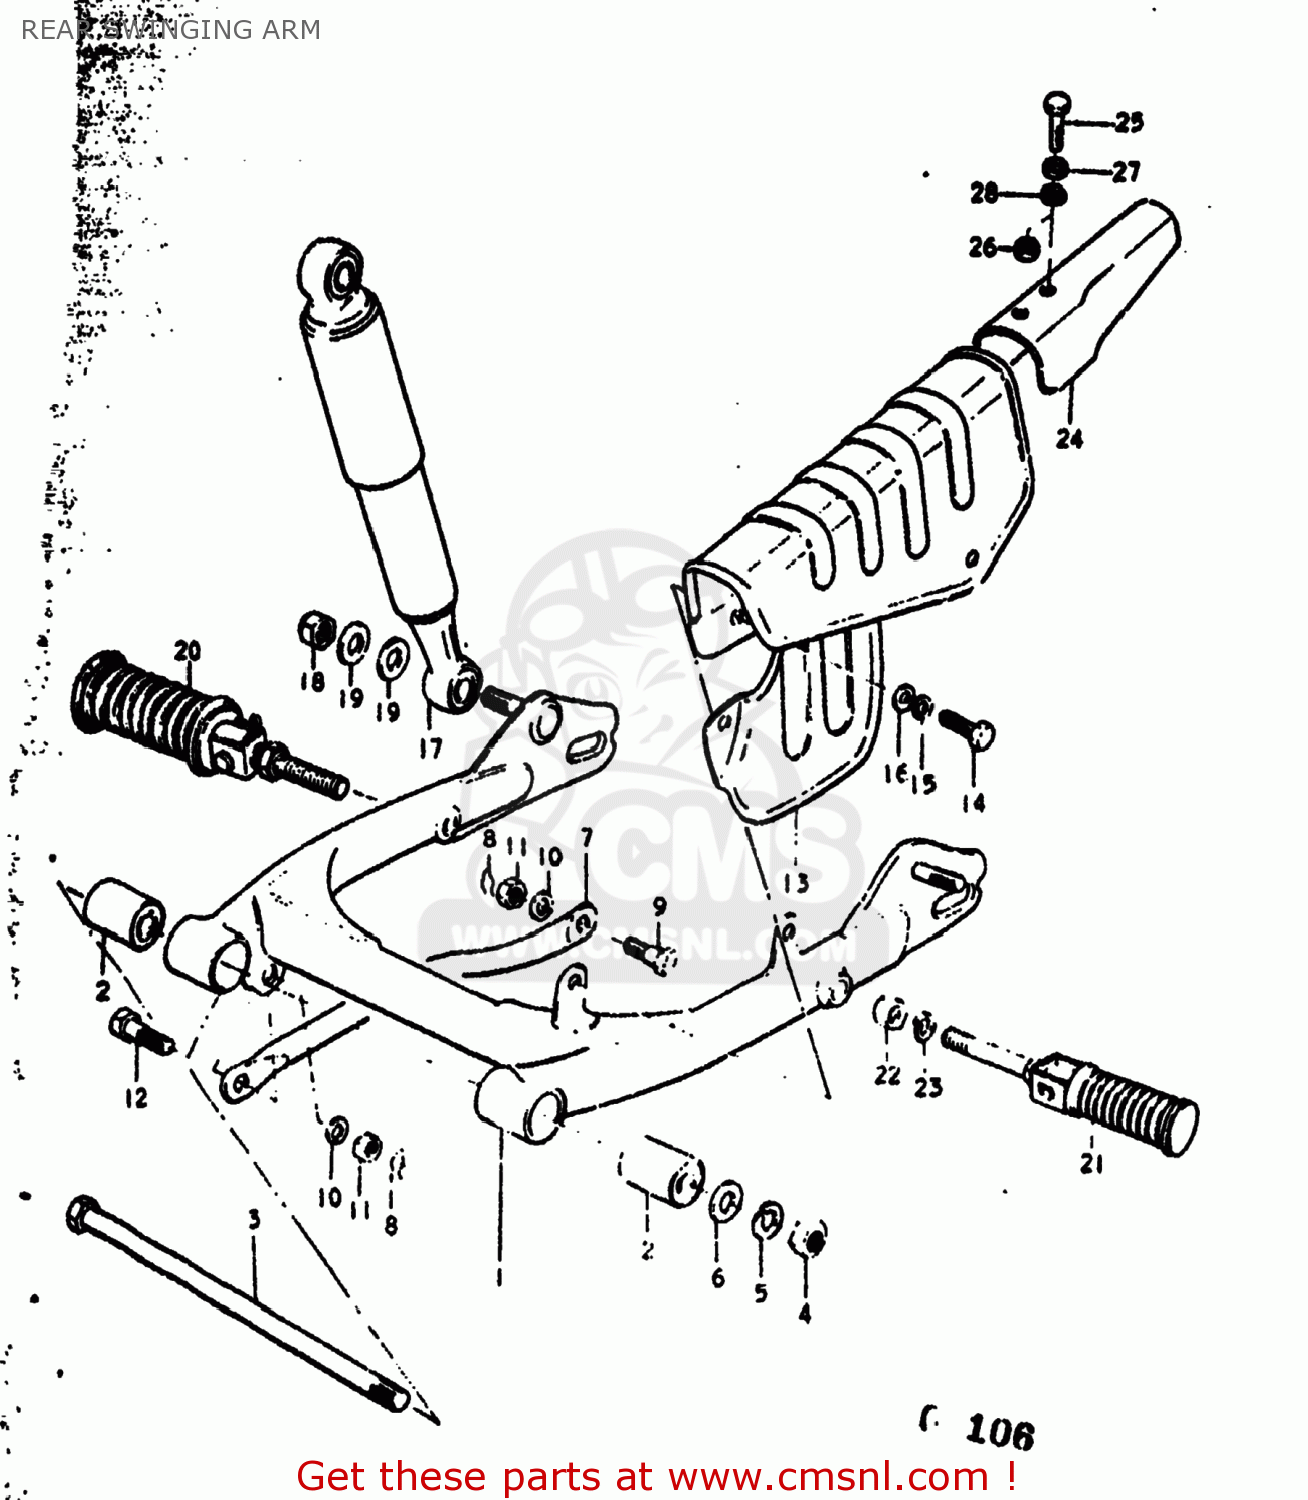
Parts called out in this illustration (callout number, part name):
1	ARM,REAR SWING
2	BUSHING(10X23X35)
3	SHAFT,REAR SWING ARM
4	NUT
5	LOCK WASHER
6	WASHER
7	TORQUE LINK,REAR
8	CLIP
9	BOLT(8X26.5)
10	LOCK WASHER
11	NUT
12	BOLT(8X29)
13	CASE,CHAIN
14	BOLT(6X8)
15	LOCK WASHER
16	WASHER
17	ABSORBER ASSEMBLY,REAR SHOCK
18	NUT
19	WASHER
20	FOOTREST ASSEMBLY,REAR
21	FOOTREST ASSY,PILLION
22	NUT
23	WASHER,LOCK 12
25	BOLT
26	NUT
27	LOCK WASHER
28	WASHER
